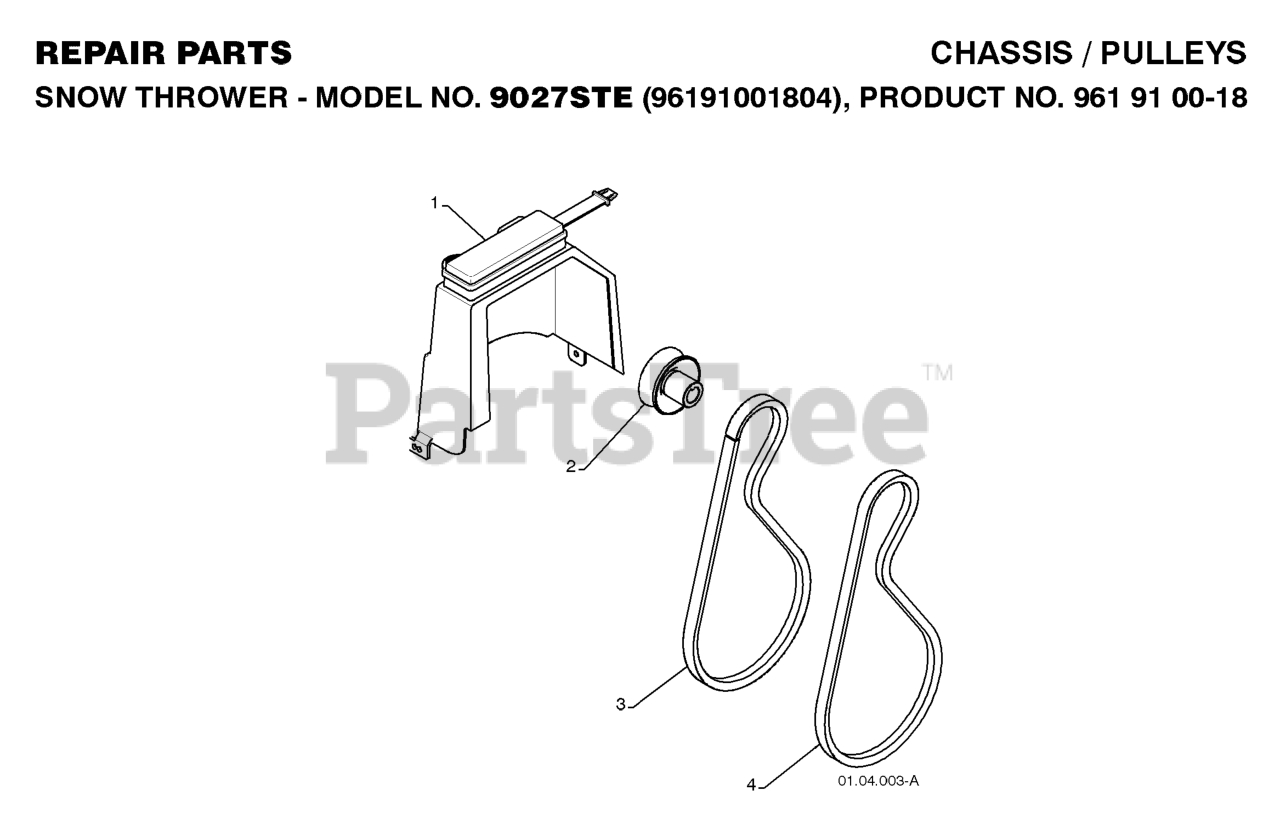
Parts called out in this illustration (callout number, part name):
1	COVER.ASM.BELT/STORAGE
2	PULLEY, ENGINE IMPELLER DRIVE
3	V-BELT TRACTION 34.25
4	BELT.V.IMPELLER
